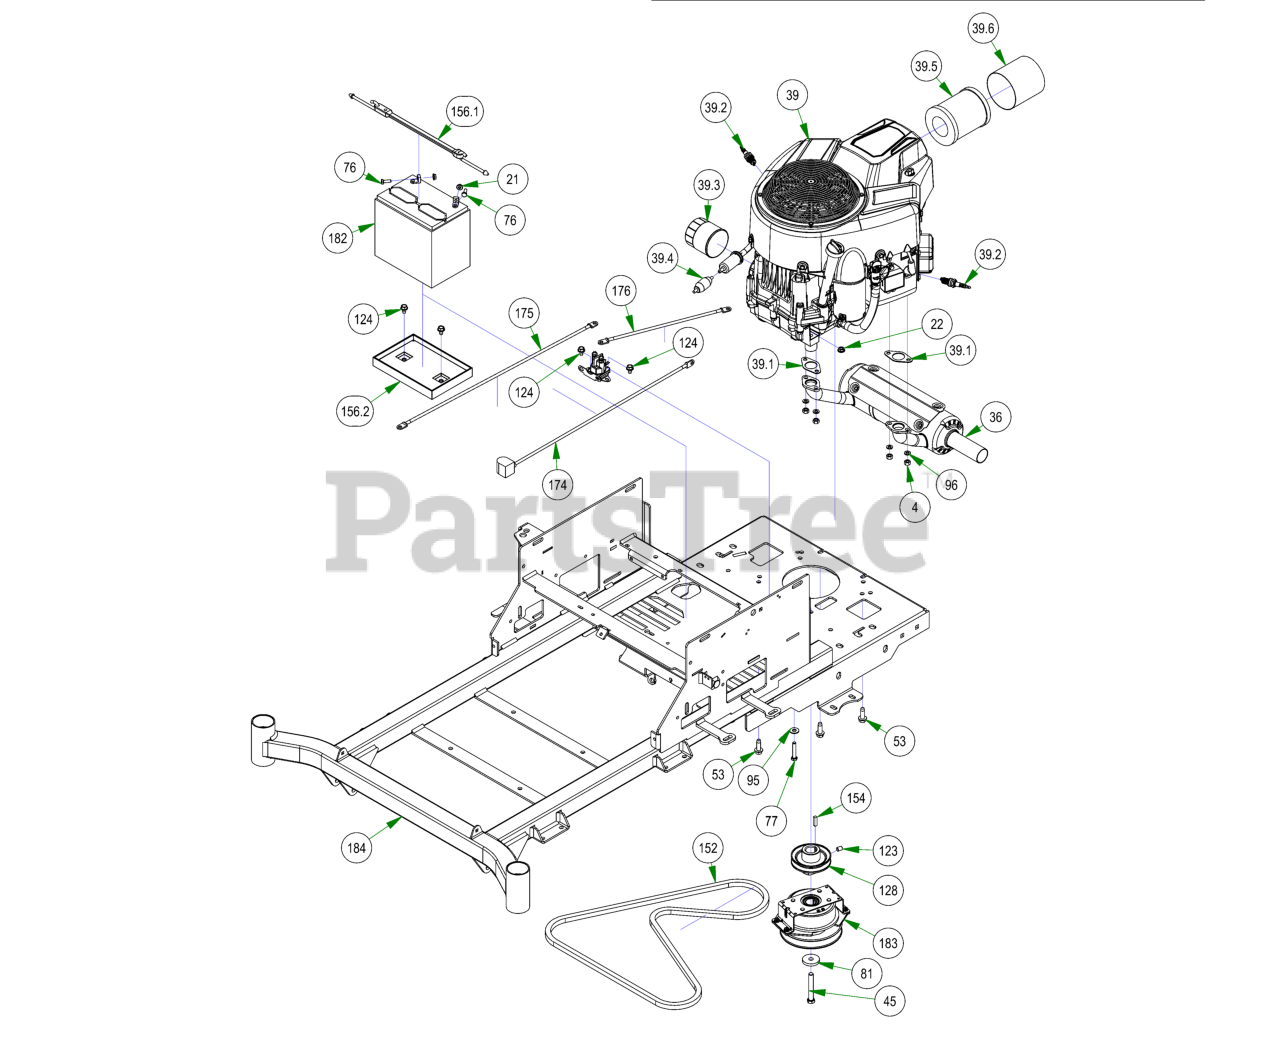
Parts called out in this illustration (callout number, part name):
4	M8-1.25 DIN 934 HEX NUT (CL.8) ZINC
21	1/4-20 HEX SERRATED FLANGE NUT HARD/ZINC
22	5/16-18 HEX SERRATED FLANGE NUT HARD/ZINC
36	2017 Compact Outlaw Exhaust 810 Vanguard
39	Vanguard 25hp CXI with out Oil Filter ZT Elite
39.1	Exhaust Gasket
39.2	Spark Plug
39.3	Oil Filter
39.4	Universal Inline Fuel Filter
39.5	Air Filter for Vanguard CXI Engine
39.6	pre-Cleaner for Vanguard CXI Engine
45	7/16-20x3” Hex Bolt GR 8 W/ Patch
53	3/8-16 X 1-1/8HEX WASHER UNSLOT SERRATED (TRI-LOB) TRS
76	1/4-20 X 3/4 HEX CAP SCREW (GR.5) ZINC
77	5/16-18 X 1-3/4 HEX CAP SCREW (GR.5) ZINC
81	CLUTCH WASHER
95	5/16 USS FLAT WASHER (7/8 OD) ZINC
96	5/16 SPLIT LOCKWASHER ZINC
123	3/8-16 X 1/2 SOCKET SET SCREW (CUP PT) PLAIN
124	5/16-18 X 1/2 HWH unslot (F) tcs zinc
128	3-3/4" Motor Pulley
154	1/4 X 1 SQ MACHINERY KEY 1018 STL PLN
156	2023 Battery Hold Down Assembly Strap
156.1	2023 Rubber Battery Hold Down Strap
156.2	Battery Tray
174	24 inch Black Cable – MZ/ZT
175	24" Red Battery Cable
176	12 in red battery cable
182	SP-35 Battery
184	2023 MZ 42-48 Frame - Painted
185	2023 MZ-Avenger 54-60 Frame - Painted
